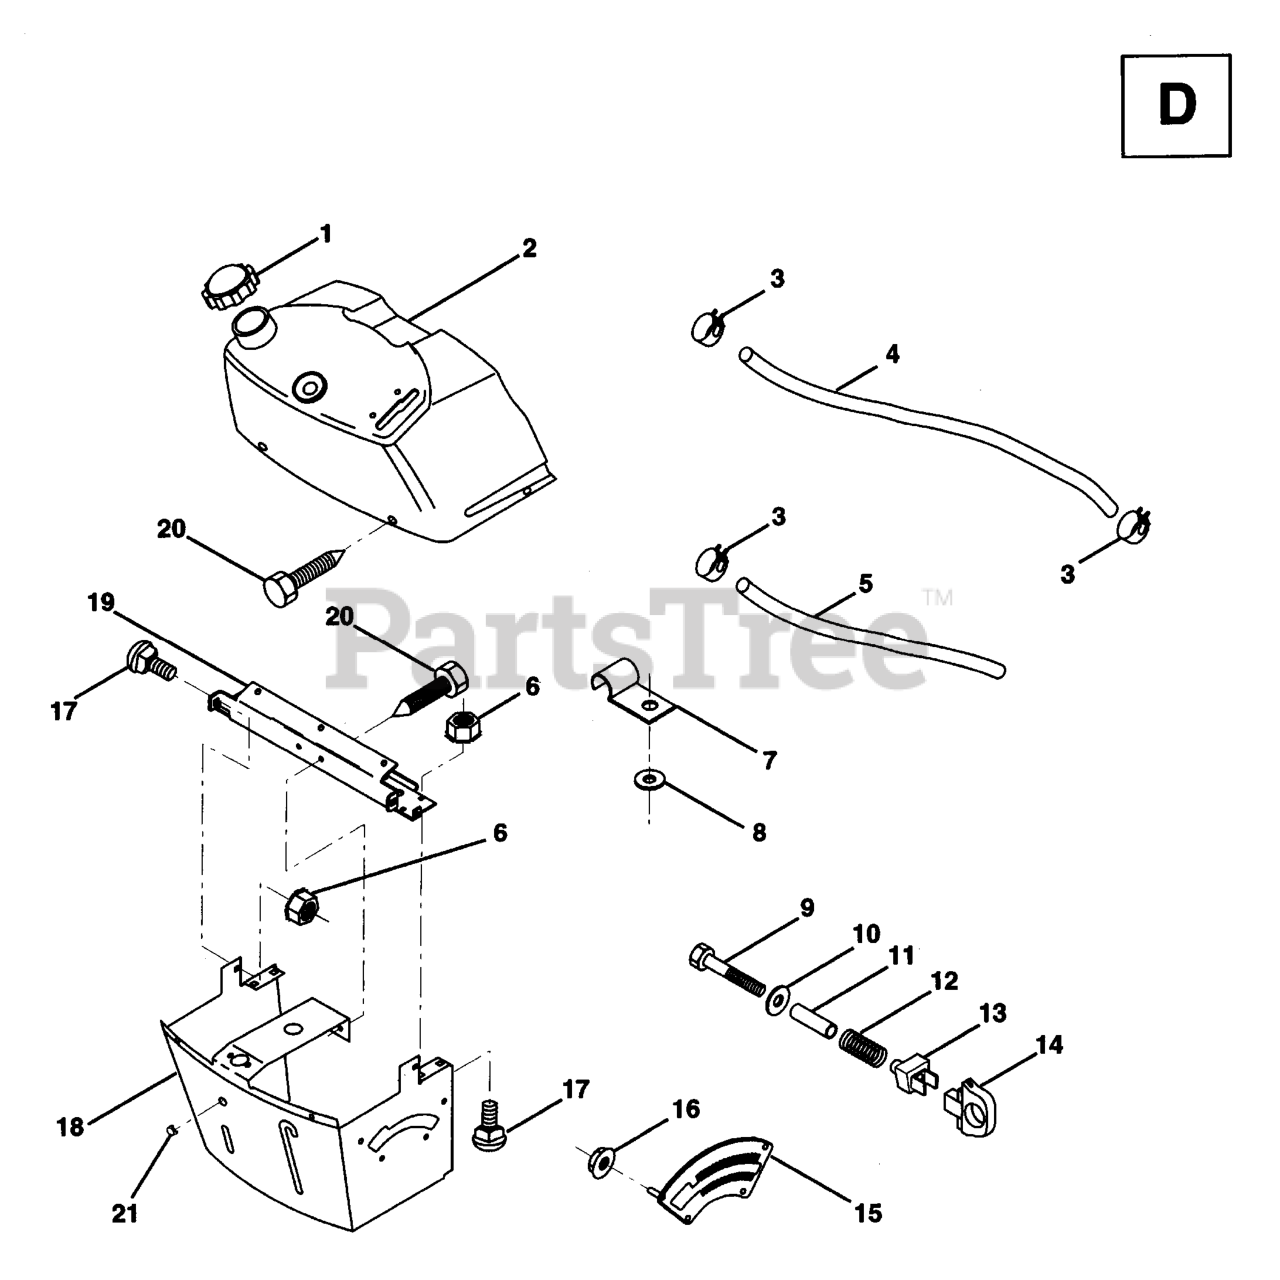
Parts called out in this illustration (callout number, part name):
1	CAP.FUEL.GREY
2	TANK ASM DASH LR
3	HOSE CLAMP
4	FUEL LINE
5	FUEL LINE T
6	NUT.CROWNLOCK.1/4
7	CLIP T
8	WASHER PM
9	BOLT HEX FIN 1/4-20X1 3/4
10	WASHER
11	SPACER SPLIT
12	SPRING.COMPRESSION
13	KNOB HGT RETAINER
15	ADJUSTER QUAD
16	NUT.PUSH.3/16
18	SUPT ASSY DASH
19	CROSS BRACE
